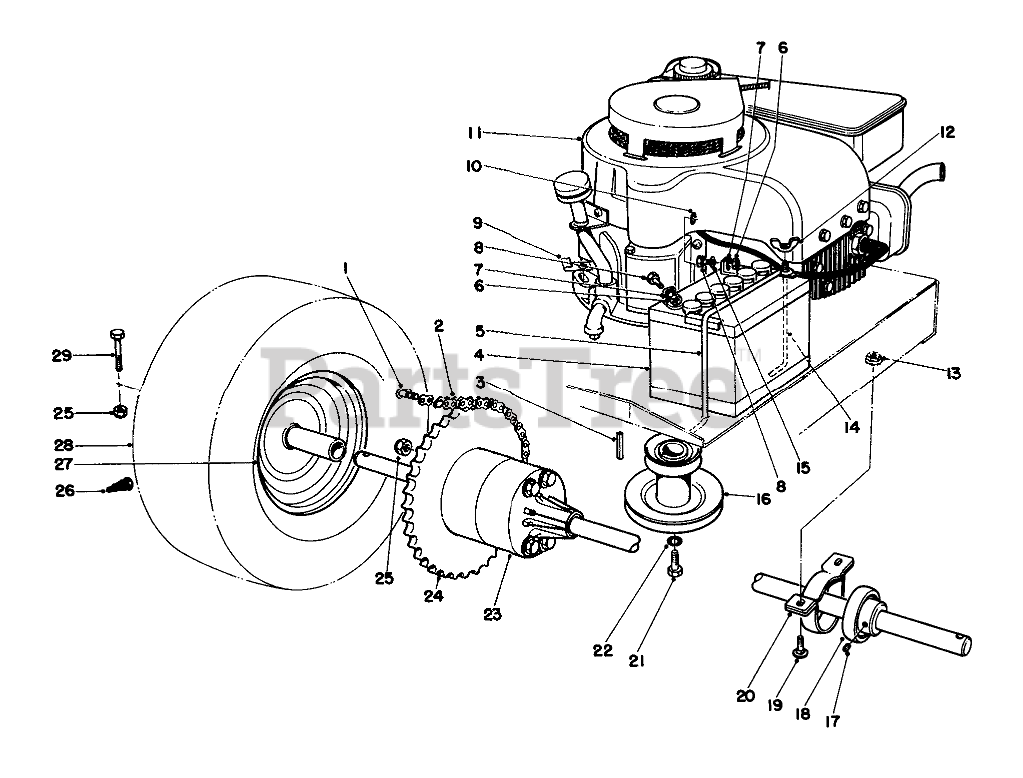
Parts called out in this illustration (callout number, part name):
1	LINK-CONNECTING
2	Chain-Roller
4	BATTERY
5	Battery Clamp
6	NUT-HEX
7	WASHER-LOCK
8	SCREW-HH
10	WASHER-LOCK/EXT
11	Engine
12	NUT-WING SPECL
13	NUT-HHF, WHIZ
14	ROD-SUPPORT, BATTERY
15	WASHER-FLAT
16	ENGINE PULLEY BO
17	Set Screw
18	BEARING-BALL
19	SCREW-CARR
20	RTNR-PILLOW BLK
21	SCREW-HH
22	WASHER-LOCK
23	Differential
24	Sprocket
25	NUT-LOCK, CONE
26	STEM-VALVE
27	WHEEL-REAR
28	Tire
29	Bolt
